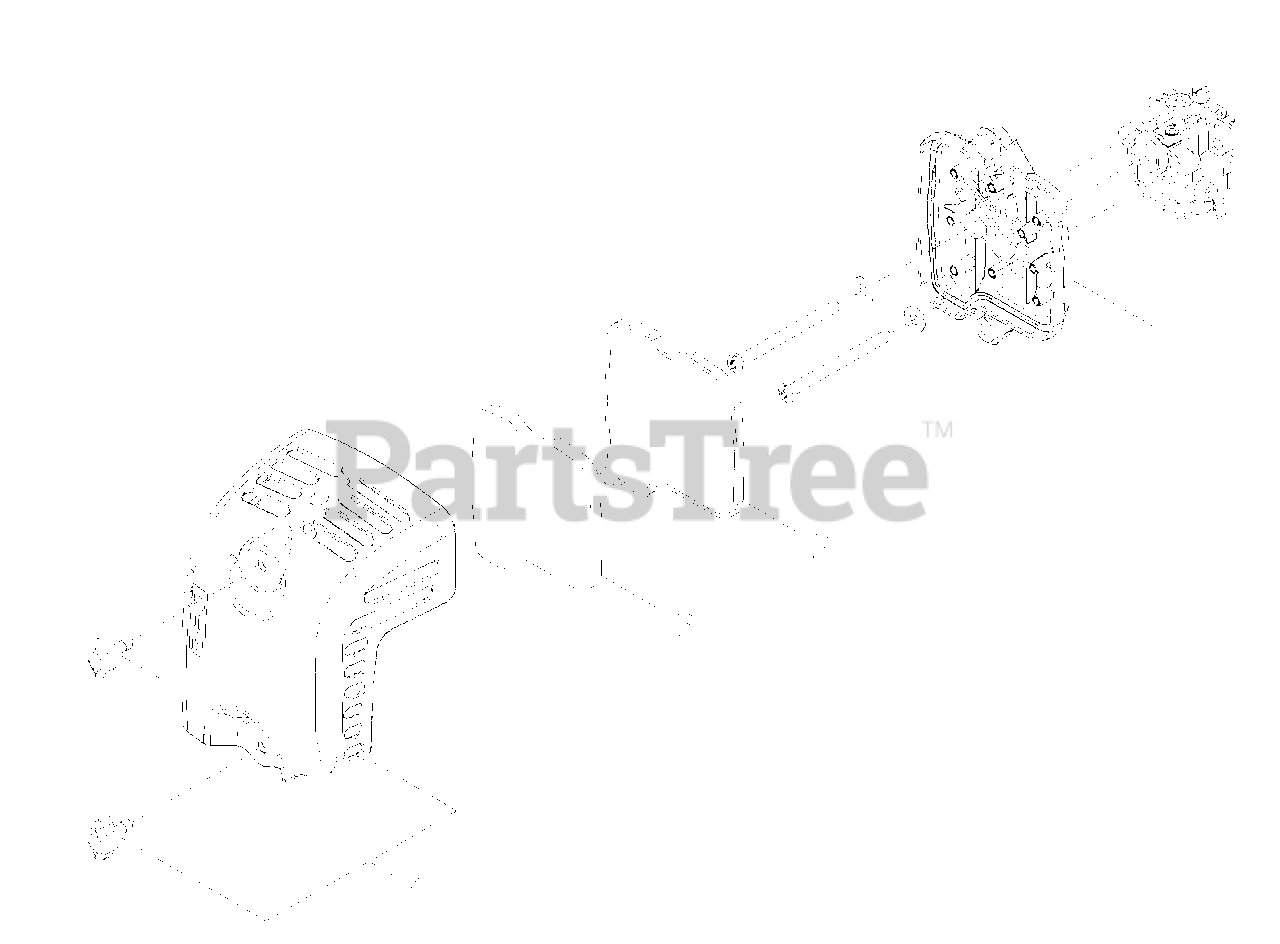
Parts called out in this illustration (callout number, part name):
1	AIR FILTER CASE ASSY
2	FILTER, AIR
3	PRE-FILTER - FOAM
4	CLEANER COVER ASSY
